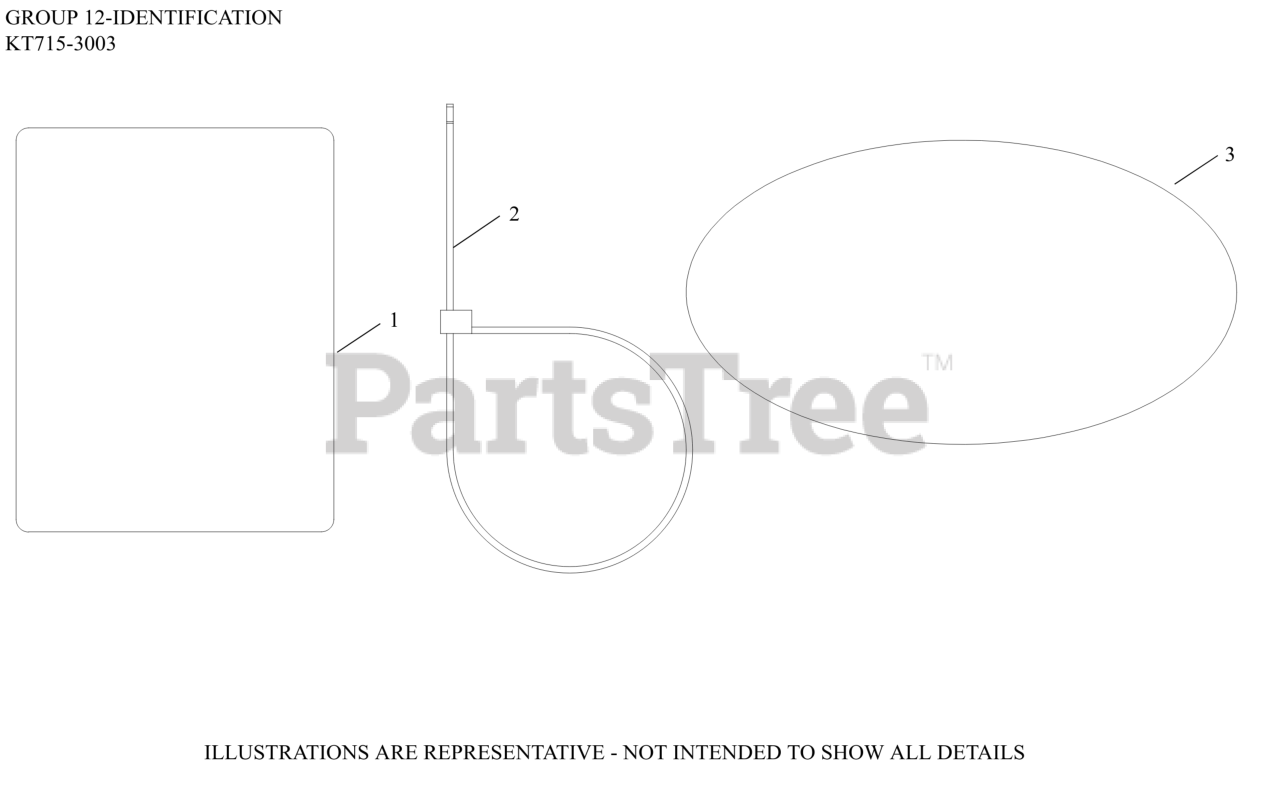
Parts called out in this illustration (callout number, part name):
1	LABEL, CLEAR LAMINATION
3	LABEL, 7000 SERIES (20HP, PRO)
3	LABEL, PRO PERFORMANCE FILTRATION SYSTEM
